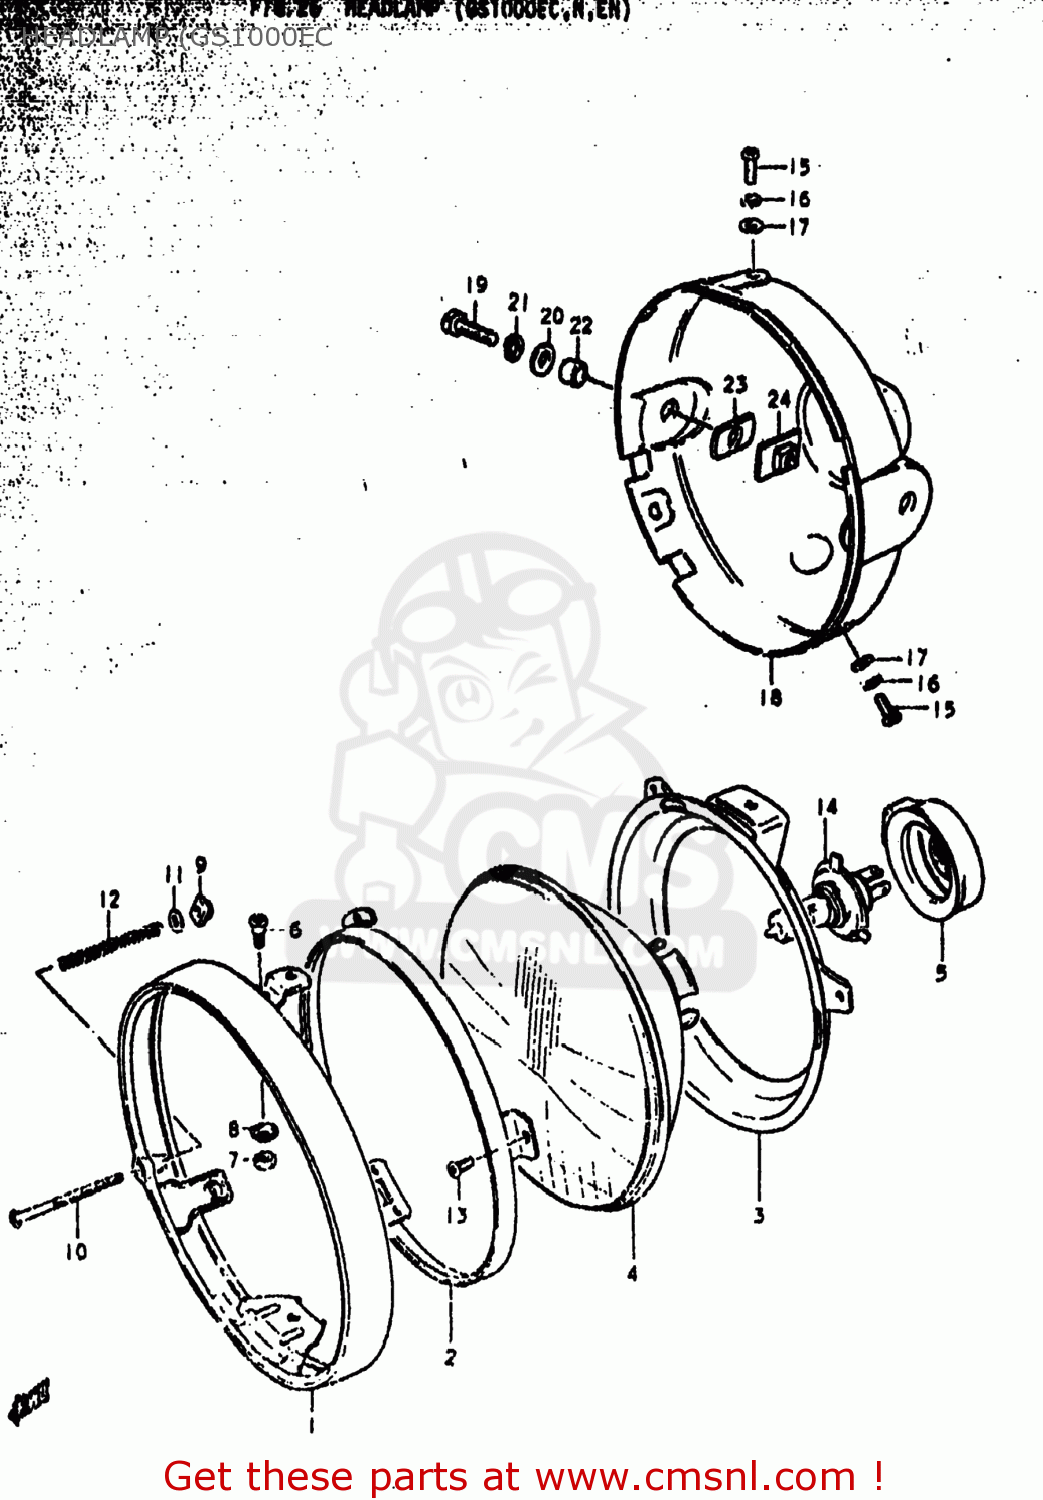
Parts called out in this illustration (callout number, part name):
1	RIM
2	RETAINER
3	RING,HEADLAMP UNIT
4	LAMP UNIT
5	COVER,HEADLAMP SOCKET
6	SCREW
7	NUT,ADJUSTING
8	SPACER
9	NUT
10	SCREW,HEADLAMP ADJUST
11	WASHER
12	SPRING,HEADLAMP ADJUST
13	SCREW
14	BULB(12V60/55W,H4)
15	SCREW
16	WASHER,LOCK
17	WASHER
18	HOUSING,HEADLAMP(BLACK)
19	BOLT
20	WASHER
21	LOCK WASHER
22	SPACER (8.8X12X7)
23	CUSHION
24	PLATE,HEADLAMP HOUSING
